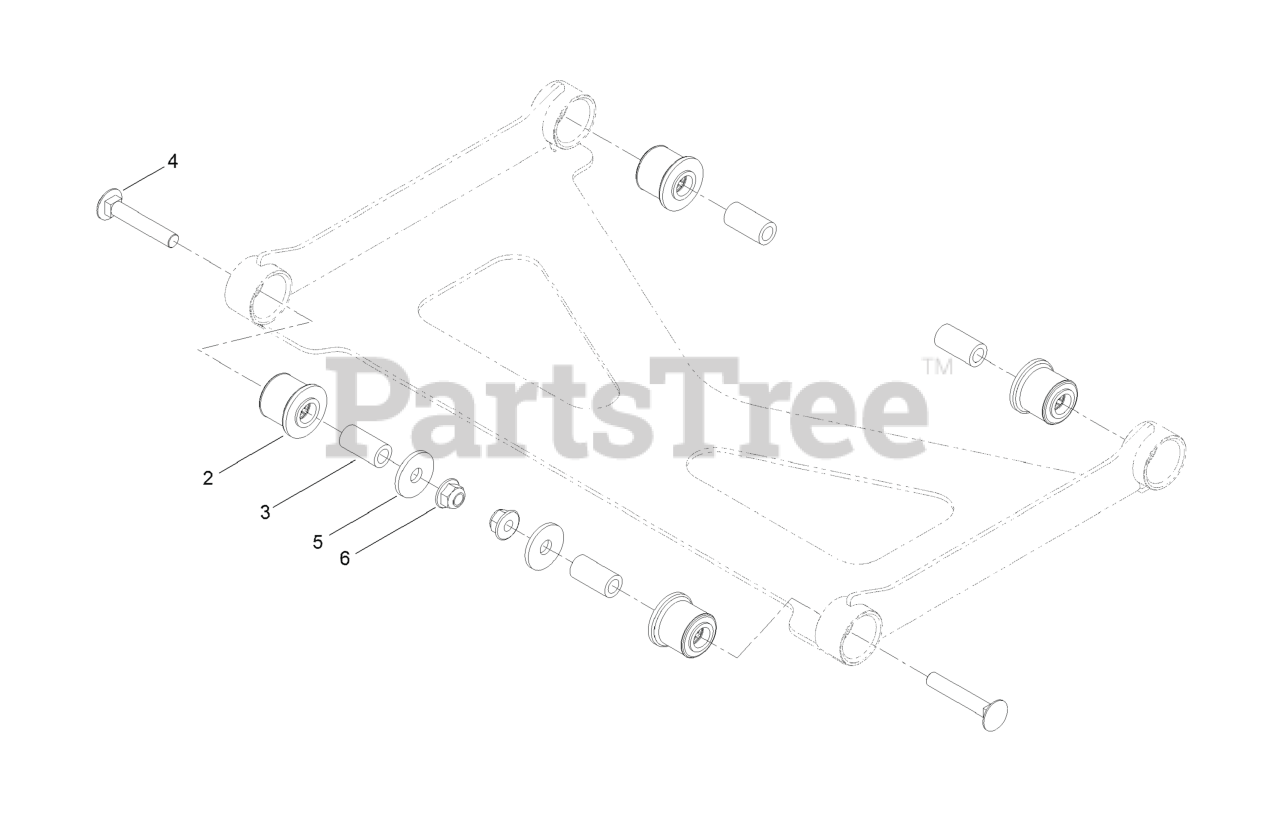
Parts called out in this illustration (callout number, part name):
2	BUSHING-RUBBER, SUSPENSION
4	Bolt-Carriage 3/8-16 X 2 1/4
5	WASHER
6	NUT-HF, NI
